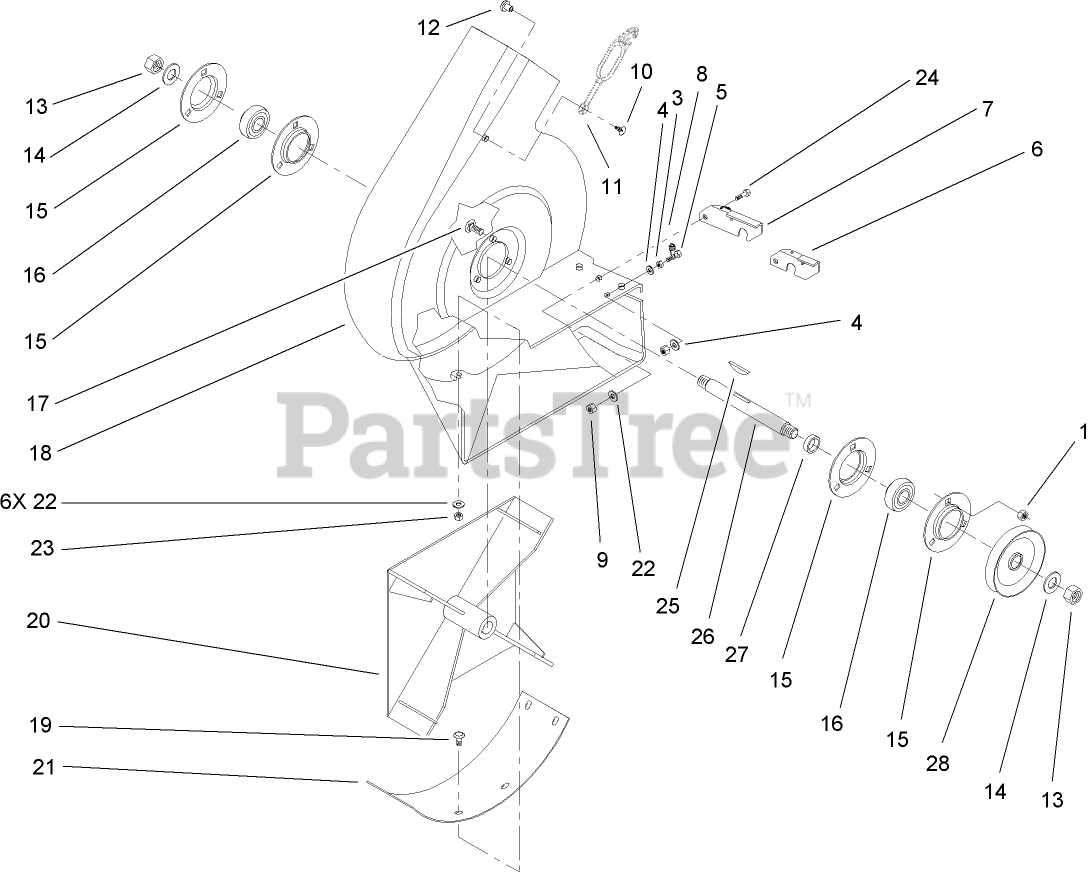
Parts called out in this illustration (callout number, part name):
1	NUT-HF
3	NUT-HEX
4	WASHER-FLAT
5	SCREW-HWH
6	LATCH-BLOWER
7	LATCH-BLOWER
8	SPRING-EXTENSION
9	NUT-LOCK, NI
10	FASTENER-PANEL
11	RETAINER-DUCT
12	SPACER-INTERLOCK
13	NUT-JAM
14	WASHER-LOCK
15	FLANGE
16	BEARING-BALL
17	SCREW-CARR
19	SCREW-CARR
20	IMPELLER ASM
21	COVER-BLOWER, BOTTOM
22	WASHER-FLAT
23	NUT-LOCK, NI
24	SCREW-HH
26	SHAFT-BLOWER
27	SPACER
28	PULLEY-BLOWER
